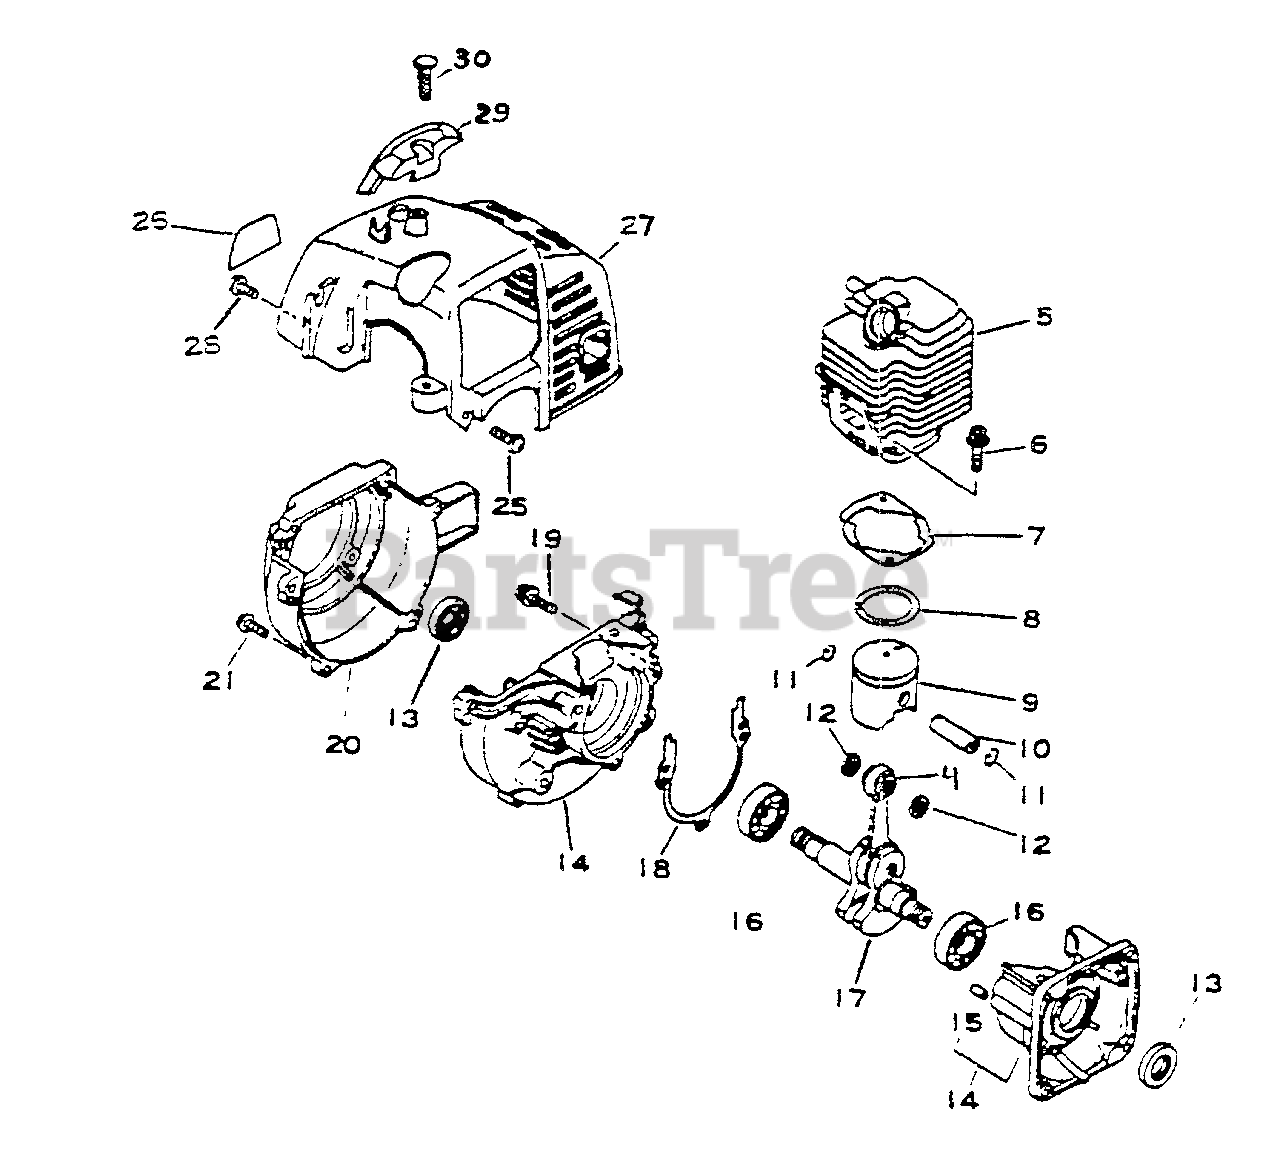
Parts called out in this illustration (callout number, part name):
4	BEARING, NEEDLE
6	BOLT 5×22
8	RING, PISTON
9	PISTON
10	PIN, PISTON 8
11	RING, SNAP
12	WASHER, THRUST
13	SEAL, OIL 12
14	CRANKCASE KIT
15	PIN, LOCATING 4×8
16	BEARING, BALL 6201
17	CRANKSHAFT ASSY
18	GASKET, CRANKCASE
19	SCREW 5×28
20	COVER, FAN - ORANGE
21	SCREW 4×16
25	SCREW 4×16
26	LABEL - MODEL
27	COVER, ENGINE
28	SCREW 4×12
29	GUARD, TOP - BLACK
30	SCREW 5×16
